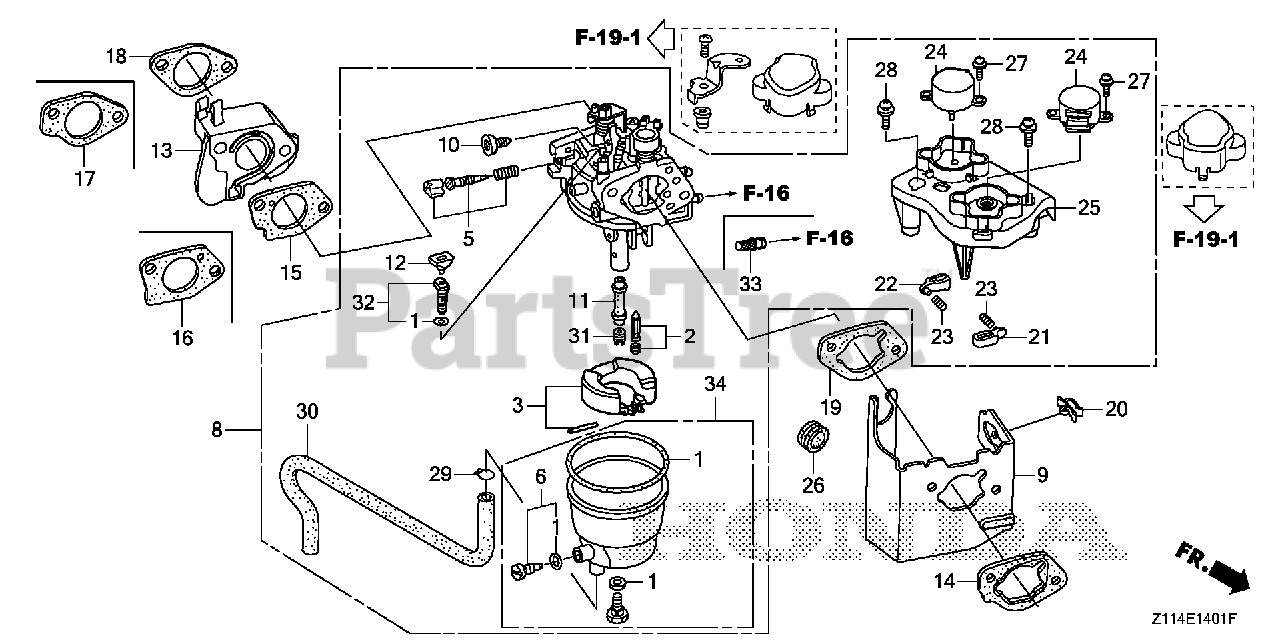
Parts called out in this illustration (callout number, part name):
1	GASKET SET
2	VALVE SET, FLOAT
3	FLOAT SET
4	CHAMBER SET, FLOAT
5	SCREW SET (Honda Code 4219879). (CARBURETOR NO.)
6	SCREW SET, DRAIN (ADVENTURE GREEN) (CARBURETOR NO.)
7	SCREW SET
8	CARBURETOR ASSY. (BE82K C/D)
9	HOLDER, TUBE
10	SCREW, STOP
11	NOZZLE, MAIN
12	COLLAR, SET
13	INSULATOR, CARBURETOR
14	SPACER, CARBURETOR
15	GASKET, CARBURETOR
18	GASKET, INSULATOR
19	GASKET, AIR CLEANER
20	CLIP B, HARNESS
21	LEVER, LINK
22	LEVER, LINK (CARBURETOR NO.)
23	SPRING, COMPRESSION COIL (CARBURETOR NO.)
24	MOTOR, THROTTLE CONTROL
25	BRACKET, THROTTLE MOTOR
26	GROMMET, FENDER
27	SCREW-WASHER (3X8)
28	SCREW-WASHER (4X12) Use up to Engine SN 2056819.
29	CLIP, TUBE (4.5)
30	BULK HOSE, VINYL (4.5X8X1000) (4.5X8X750)
31	JET, MAIN (#88) Use up to Engine SN BE81B B.
31	JET, MAIN (#90) Use from Engine SN BE81B C.
31	JET, MAIN (#92)
32	JET SET, PILOT (#45)
34	BOLT KIT
34	BOLT KIT, FUEL CHAMBER
